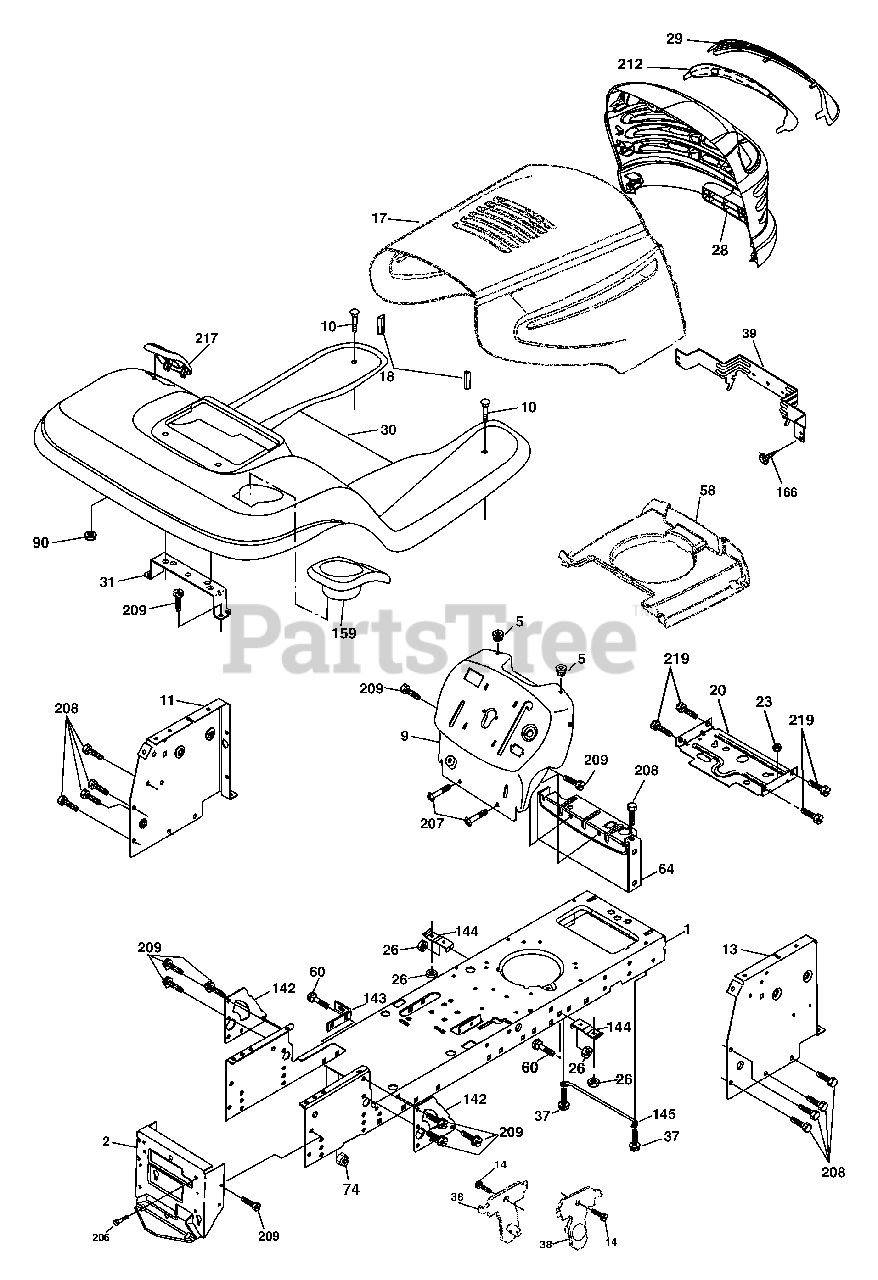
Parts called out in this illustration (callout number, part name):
1	Chassis
2	Drawbar
5	Bumper Hood/Dash
9	Dash P/L
10	Bolt Carriage 3/8-16 x 1
11	Panel Dash Lh
13	Panel Dash Rh
14	Screw Thdrol 3/8-16 x 1/2
17	Hood
18	Bumper Hood
20	Plate Battery
23	Bushing
26	Nut Lock Hex W/Ins 3/8-16 unc
28	Grille/Lens Asm
29	Lens Grille
30	Fender Footrest STLT Pnt
31	Bracket Fender
37	Screw Thdrol 6/16-18 x 1/2 TYT
38	Bracket Asm Pivot Mower Rear
39	Bracket Pivot
58	Duct Air
60	Bolt RDHD Sqnk 3/8-16 unc x 3/4
64	Dash Lower STLT
74	Nut Crownlock 3/8-16 unc
90	Nut Self Thd Wsh - HD 1/4 Zinc
142	Plate Reinforcement STLT
143	Bracket Swaybar Chassis
144	Bracket Footrest Step-thru
145	Rod Pivot Chassis/Hood
159	Cupholder
166	Screw Hwhd Hi-Lo #13-16 x 3/4
206	Bolt Shoulder 5/16-18
207	Screw Thdrol 5/16-18 x 1/2
208	Screw Thdrol 3/8-16 x 1/2
209	Screw Hexwsh Thdr 3/8-16 x 3/4
212	Insert Lens Refl.
217	Console Fuel Window
219	Screw 5/16-18 x 3/4
